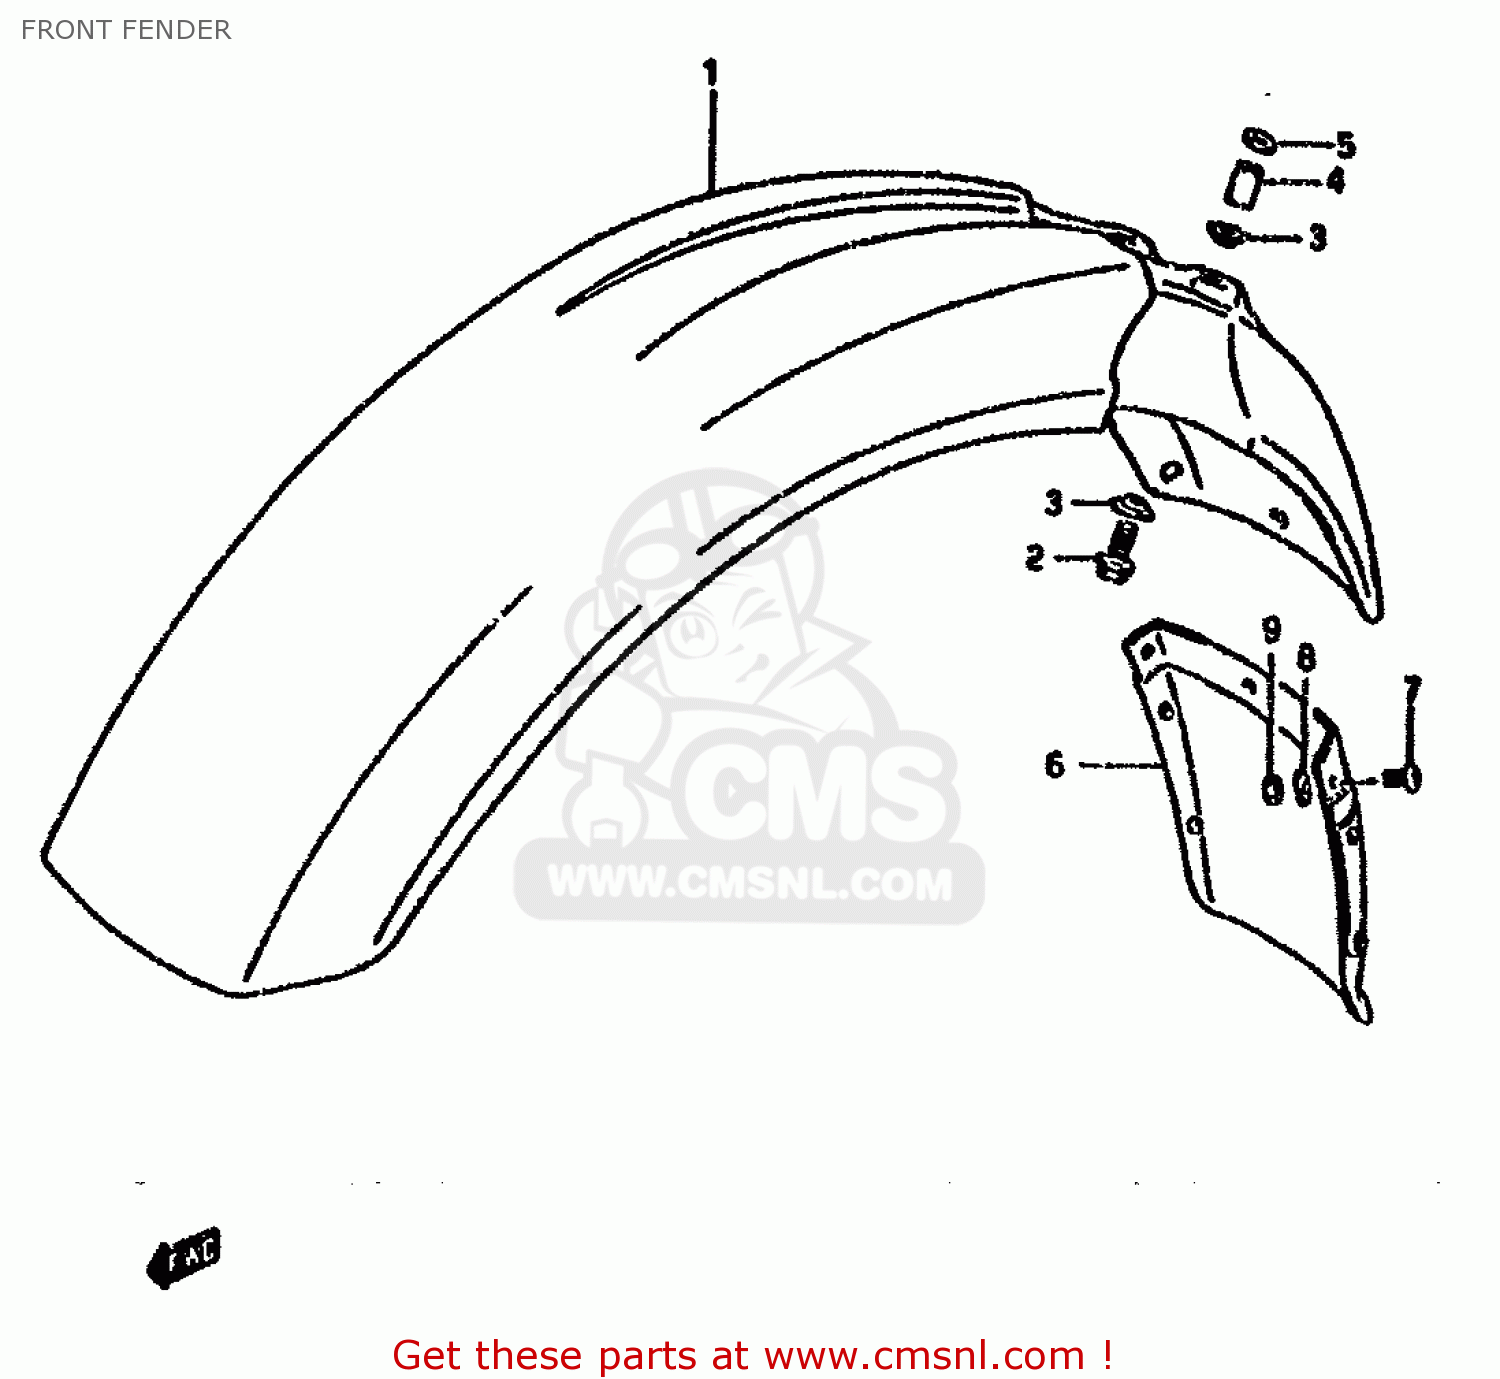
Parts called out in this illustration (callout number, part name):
1	FENDER,FR
2	BOLT
3	WASHER
4	SPACER (6.8X10X16)
5	WASHER
6	MUD GUARD,FRONT FENDER
7	SCREW(5X10)
8	WASHER
9	NUT
